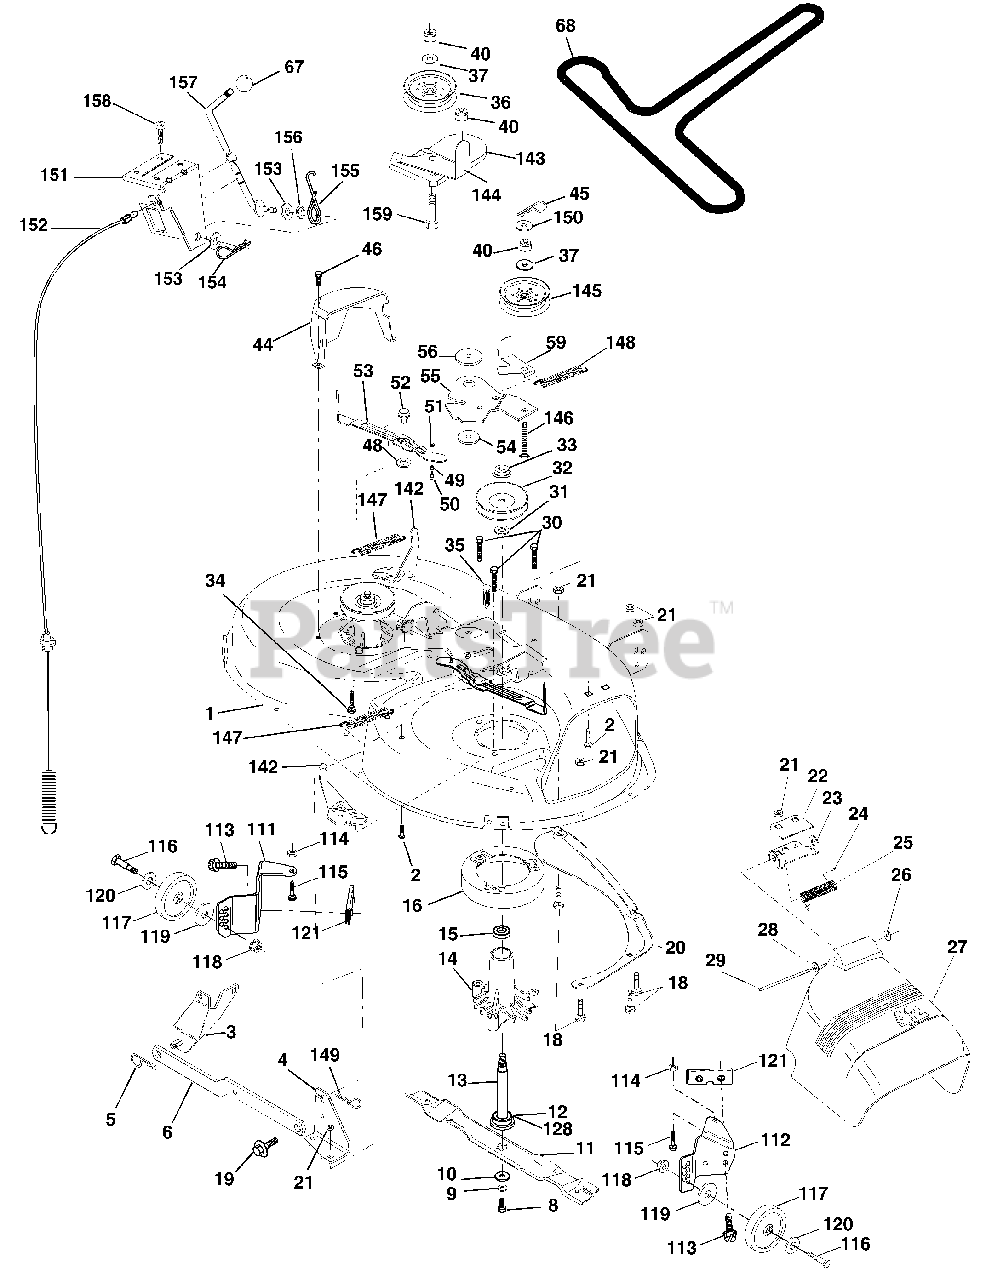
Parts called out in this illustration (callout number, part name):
1	Mower Deck Assembly, 42"
2	Bolt
3	Bracket Asm Fr. Sway Bar 3/42
4	Bracket Asm Deck 42" Sway Bar
5	Retainer Spring
6	Arm, Suspension, Rear
8	Bolt 3/8-24 x 25 Grade 8 patched
9	Washer, Lock
10	Washer, Hardened
11	Blade
12	Bearing, Ball #6204
13	Shaft Assembly, Mandrel, Vented
14	Housing, Mandrel, Vented
15	Bearing, Ball, Mandrel
16	Stripper, Vented Mower Deck
18	Bolt, Carriage 5/16-18 x 5/8
19	Bolt, Shoulder
20	Baffle, Vortex
21	Nut
22	Stiffener Bracket
23	Bracket, Deflector Mower 42"
24	Cap, Sleeve 80 x 112 Blk Mower
25	Spring, Torsion, Deflector 2 52
26	Nut, Push Phos & Oil
27	Shield, Deflector 42" Blk
28	Washer 11/32 x 5/8 x 16 Gauge
29	Rod, Hinge 42" 6 75 W/G
30	Screw Thdrol Washer Head
31	Washer, Spacer Mower Vented
32	Pulley, Mandrel
33	Nut, Toplock 9/16
34	Bolt
35	Fastener, Christmas Tree
36	Pulley, Idler, Flat
37	Washer 13/32 x 13/16 x 16 Gauge
40	Nut
44	Guard, Mandrel, LH
45	Retainer
46	Screw, Thdrol 1/4-20 x 5/8 T
48	Washer, Hardened
49	Roller Assembly, Cam Follower
50	Bolt, Shoulder #10-24 Grade 5
51	Locknut
52	Bolt, Shoulder 5/16-18 UNC
53	Arm Assembly, Pad, Brake
54	Washer, Hardened
55	Arm, Idler
56	Spacer, Retainer
59	Guard TUV Idler
67	Knob
68	V-Belt, 42" Mower
111	Bracket Gauge Wheel Lh
112	Bracket Gauge Wheel Rh
113	Screw 5/16-18 x 3/4
114	Nut Keps 5/16-18unc
115	Bolt Carr 5/16-Unc x 1/2
116	Bolt Shld
117	Wheel Gauge Blk
118	Nut Centerlock 3/8-16unc
119	Washer 3/8 x 7/8 x 14 Ga.
120	Washer 17/32 x 15/16 x 12 Ga.
121	Bracket Extruded Gauge Wheel
128	Washer, Felt
142	Arm Spring Brake Mower
143	Bracket Arm Idler 42"
144	Keeper Belt 42" Clutch Cable
145	Pulley Idler Flat
146	Bolt Carriage Idler
147	Spring Extension
148	Spring Return Idler
149	Retainer Spring Yellow
150	Washer 9/32 x 3/4 x 16 Ga.
151	Bracket Clutch Cable
152	Clutch Cable 42"
153	Washer Flat 3/8" Type B
154	Spring Retainer
155	Spring Retention LVR CLTCH CAB
156	Spacer Clutch Cable
157	Rod Clutch Cable 3/8"
158	Screw Hex Thd Cut 1/4-20 x 5/8
159	Bolt Rdhd Sqn 3/8-16 UNC x 1-3/4
